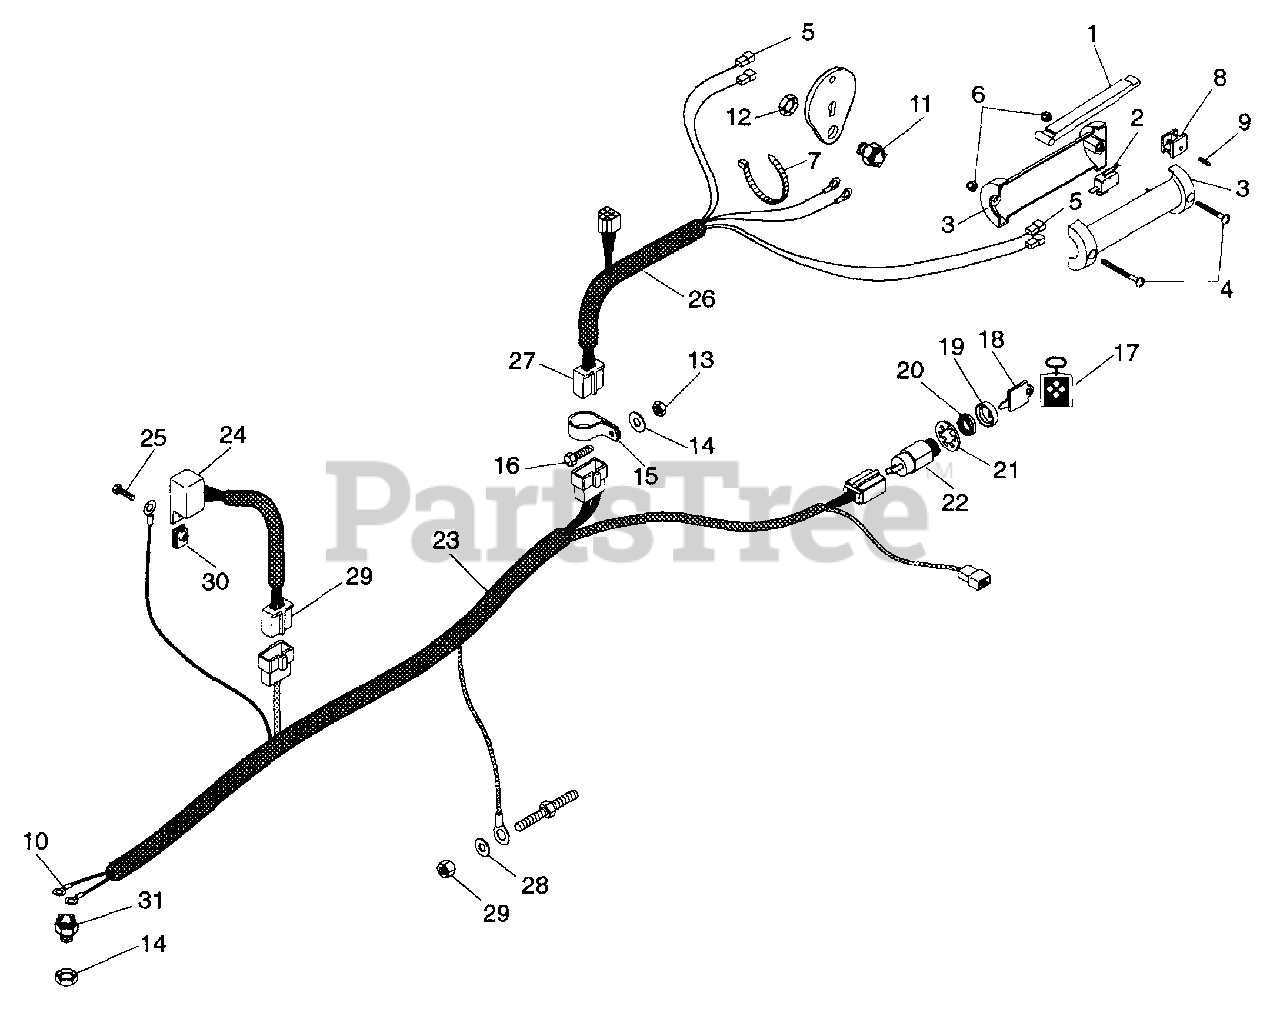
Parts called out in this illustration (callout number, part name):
1	Lever
2	Switch
3	Handle, Left Hand & Right Hand
4	Screw-Machine 10-24 x 1.50
5	Terminal, Female
6	Nut-Locking-Flange .250-20
7	Tie Wrap, Black
8	Holder Switch
9	Pin-Roll .094 x .750
10	Terminal, Eyelet
11	Switch, Interlock Closed
12	Nut-Stamped .56-18
13	Nut-Locking-Nylon .250-20
14	Washer-Flat-Steel .281 x .620 x .065
15	Cable Clamp
16	Bolt-Hex .25-20 x .75 Grade 5
17	Key Chain
18	Ignition Switch Key
19	Cap-lgnition Switch
20	Nut-Panel .625-32
21	Washer-Lock-lnternal .625 x .045
22	Key Switch Assembly
23	Harness, 10-HP Kawasaki
24	Module, Interlock Recoil
25	Bolt-Hex .25-20 x .63
26	Harness, Wiring Handle Bar
27	Terminal
28	Washer-Flat-Steel .469 x .938 x .065
29	Nut-Locking-Nylon .375-16
30	Nut-Speed .25-20
31	Switch, Interlock Open
